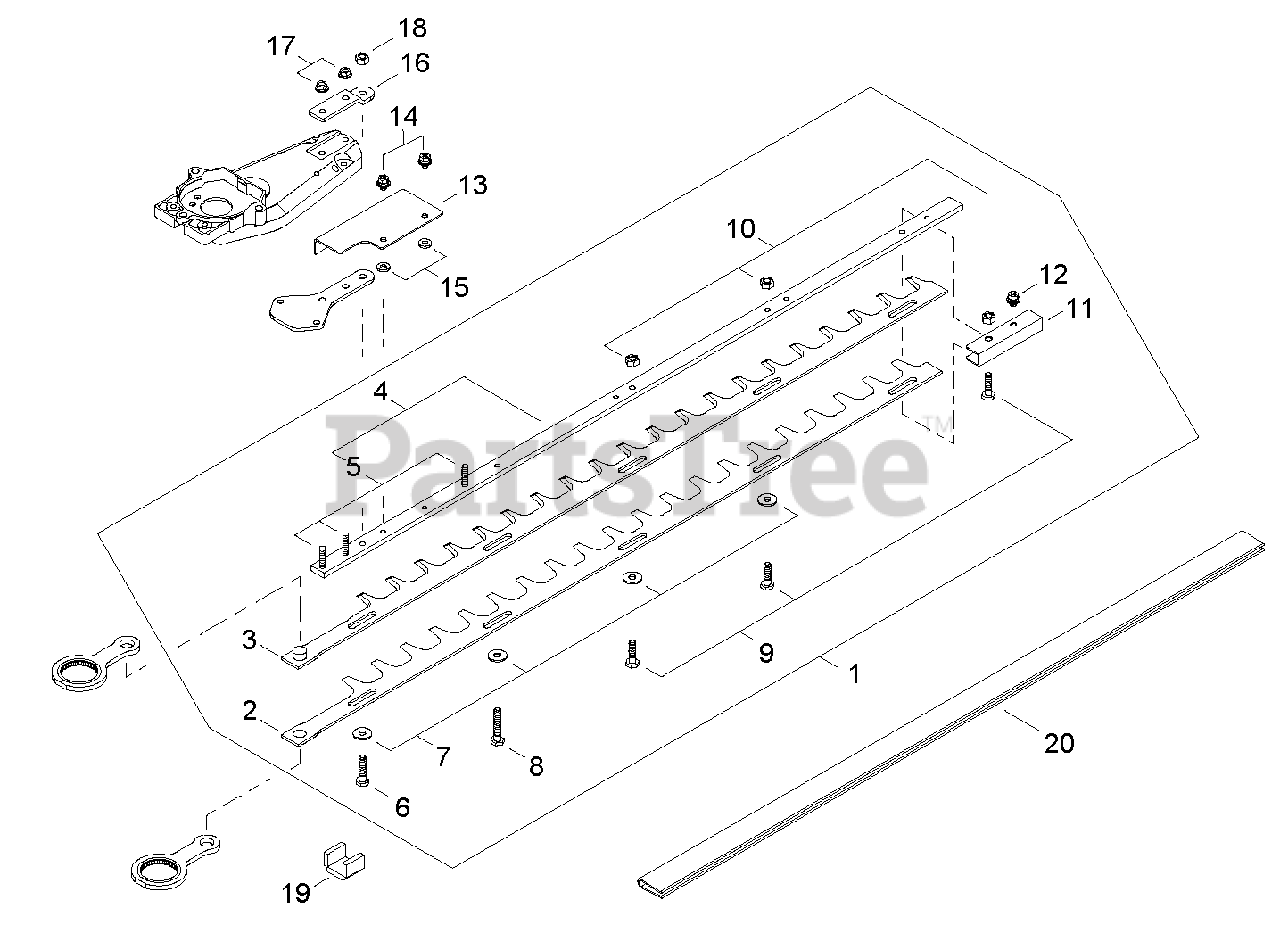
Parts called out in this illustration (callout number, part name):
1	BLADE KIT - 30" (76cm) CHROME
2	BLADE - 30" CHROME -- LOWER
3	BLADE - 30" CHROME -- UPPER
4	SUPPORT ASSY - 30"
5	SCREW - 5X25
6	BOLT - 6
7	WASHER - 6
8	BOLT - 6X32
9	BOLT - 6X20
10	NUT - 6
11	PLATE, GUIDE
12	SCREW - 5X8
13	PROTECTOR
14	SCREW - 5X8
15	WASHER - VINYL
16	PLATE, ANGLE
17	NUT - 5 -- FLANGE
18	NUT - 6
19	SEAL, FELT
20	COVER, BLADE - 30" (76cm)
